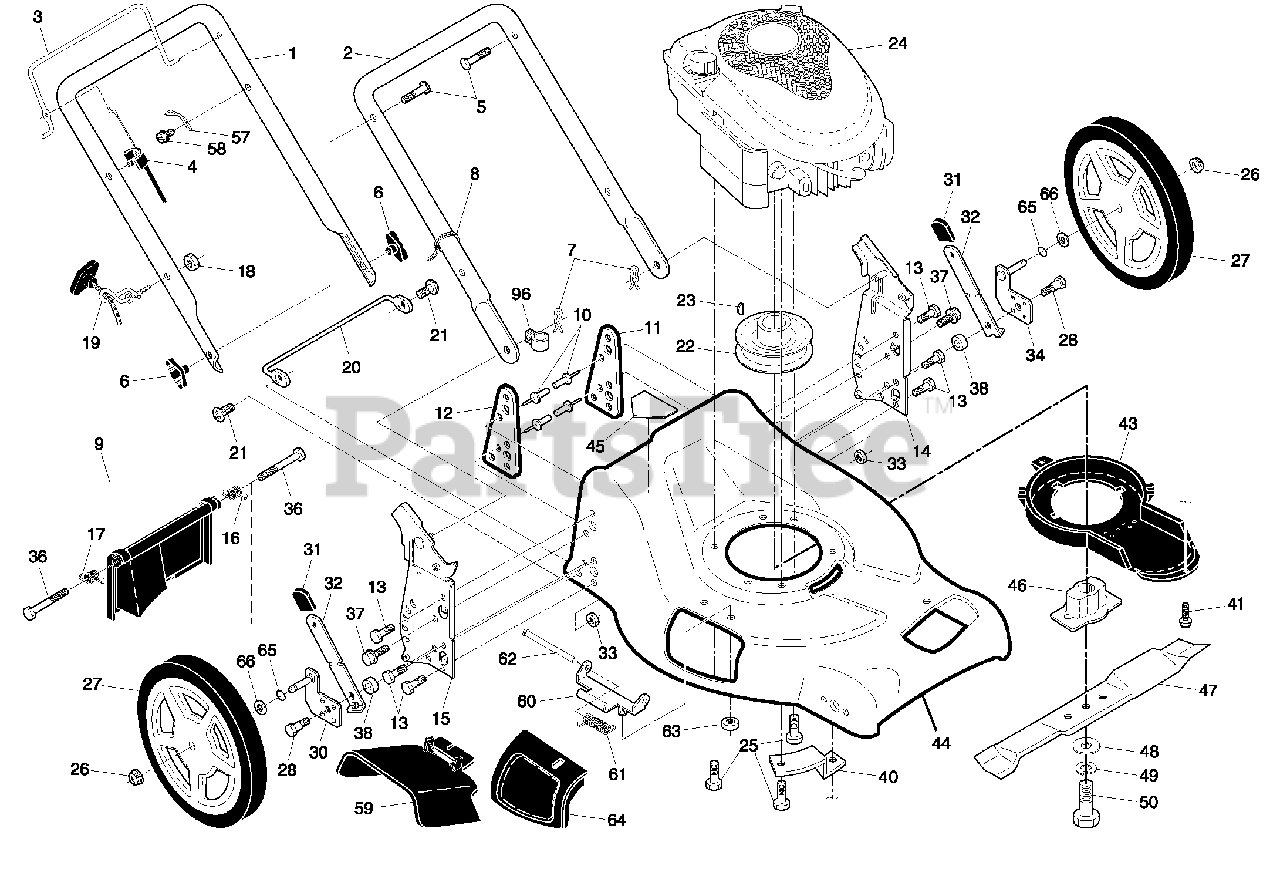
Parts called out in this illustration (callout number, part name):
1	Upper Handle
2	Lower Handle
4	Engine Zone Control Cable
6	Handle Knob
7	Hairpin Cotter
8	Wire Tie
9	Rear Door Kit
11	Support Bracket, LH
12	Support Bracket, RH
13	Screw 1/4-20 x 5/8
14	Handle Bracket Assembly, LH
15	Handle Bracket Assembly, RH
16	Spring, Rear Door, LH
17	Spring, Rear Door, RH
18	Keps Locknut 1/4-20
19	Rope Guide
20	Foot Guard, C.E.
21	Screw, Tapping 1/4-20 x 1/2
22	Engine Pulley
25	Hex Head Thread Rolling Screw 3/8-16 x 1-1/8
26	Hex Flange Nut
27	Wheel & Tire Assembly
28	Shoulder Bolt 5/16-18 x .33
30	Axle Arm Assembly, Rear, RH
31	Selector Knob
32	Selector Spring
33	Nut, Hex 5/16-18
34	Axle Arm Assembly, Rear, LH
36	Bolt, Hex Head
37	Screw 5/16-18 x 3/4
40	Mounting Bracket, Debris Shield
43	Debris Shield
44	Kit, Housing
45	Danger Decal
46	Blade Adapter
47	Blade, 21"
48	Hardened Washer
49	Helical Washer 3/8-24 x 1-3/8 Grade 8
50	Hex Head Machine Screw 3/8-24 x 1-3/8 Grade 8
57	Bracket, Upstop
58	Screw, Threaded 10-24 x 1/2
59	Discharge Deflector
60	Hinge Bracket
61	Spring, Torsion
63	Nut, Hex
96	Operator's Manual, European
96	Operator's Manual, Scandinavian
96	Repair Parts Manual, English
